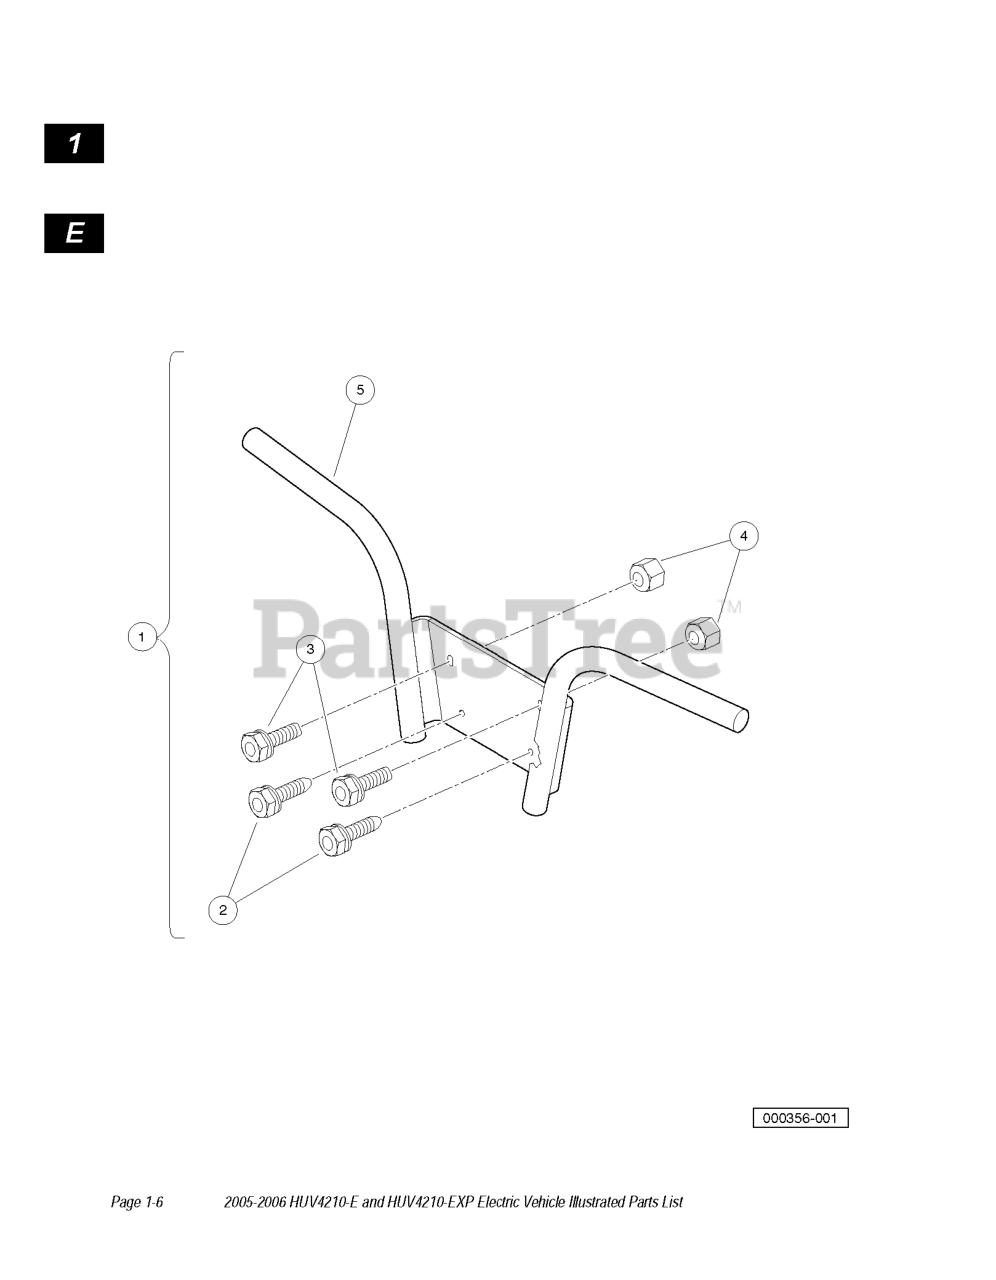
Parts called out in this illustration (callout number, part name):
1	Kit, Brush Guard
2	SCREW, M8 X 1.25 X 30 TRI, BLK
3	BOLT, FLANGE HD, M8 X 40.0
4	LOCK NUT, FLG M8 X 1.25 NYLON
6	Instr, Brush Guard
